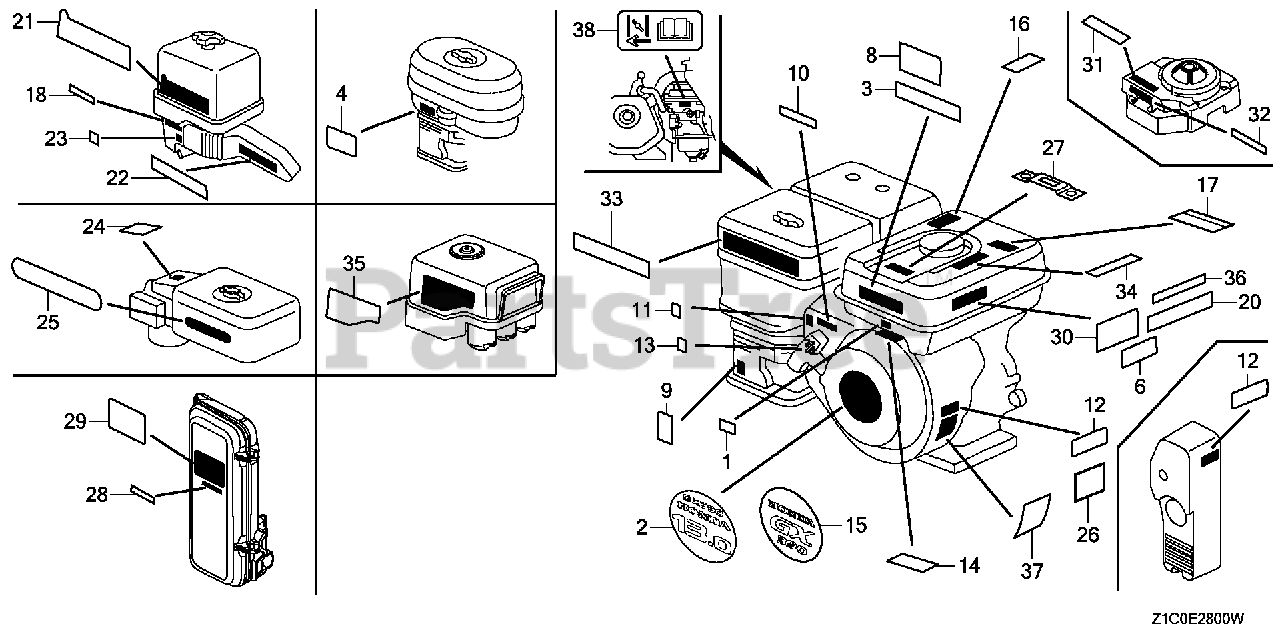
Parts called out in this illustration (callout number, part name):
2	EMBLEM (GX390) (HONDA)
3	LABEL, CAUTION
6	MARK, OIL ALERT (ENGLISH)
9	MARK, CHOKE (EXTERNAL)
